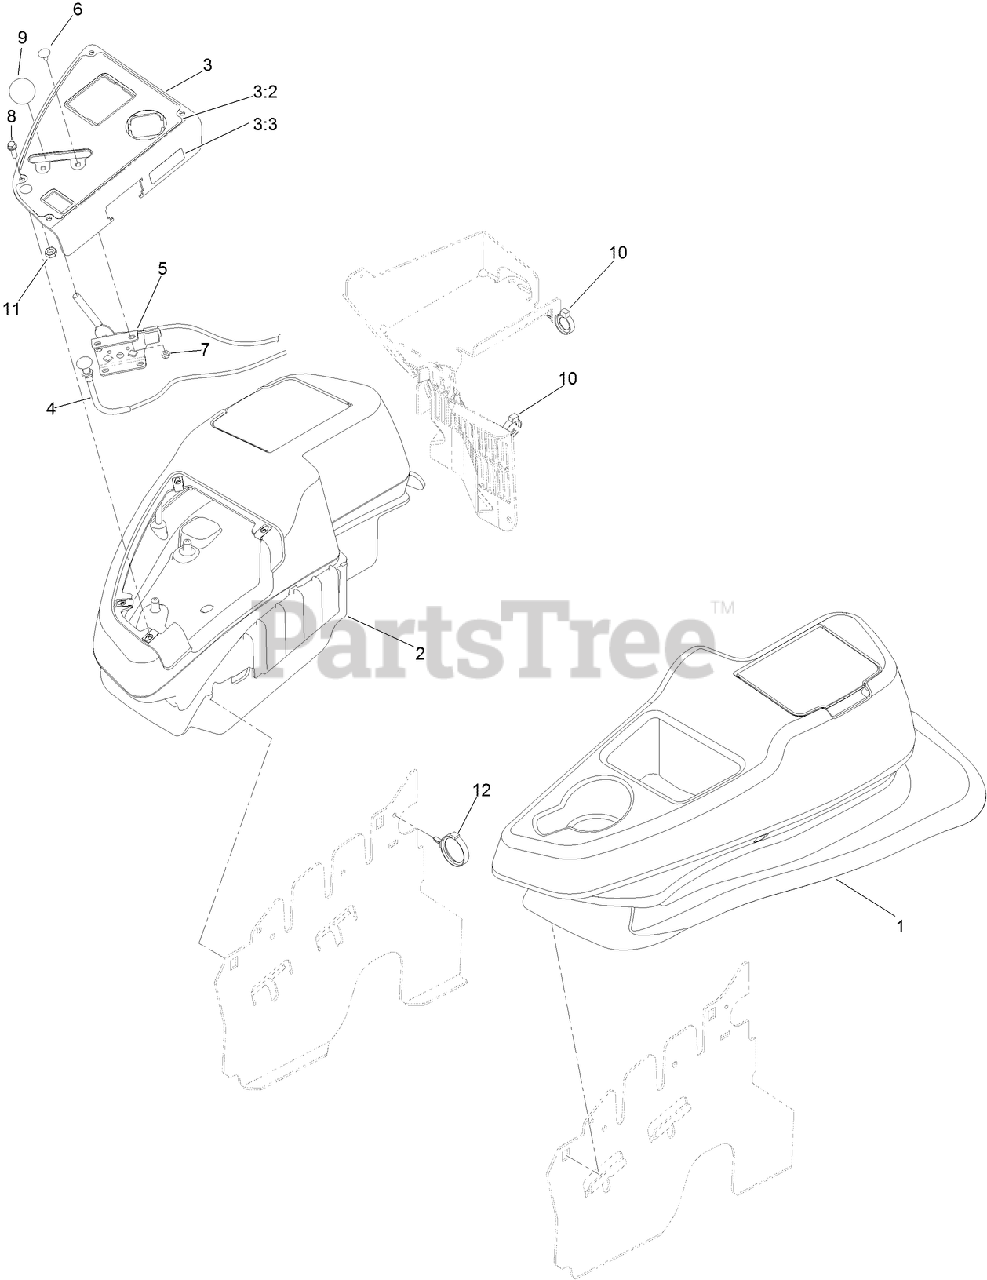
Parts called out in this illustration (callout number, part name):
1	LH CONSOLE ASM
2	RH CONSOLE ASM
3	CONTROL PANEL ASM
3:2	DECAL-PANEL, CONTROL
3:3	DECAL-FUSES
4	CONTROL-CHOKE
5	THROTTLE-CONTROL
6	BOLT-CARR
7	NUT-LOCK, NI
8	SCREW-HWH
9	KNOB-BALL
10	CLAMP-HOSE
11	NUT-HJ
12	CLAMP-HARNESS
